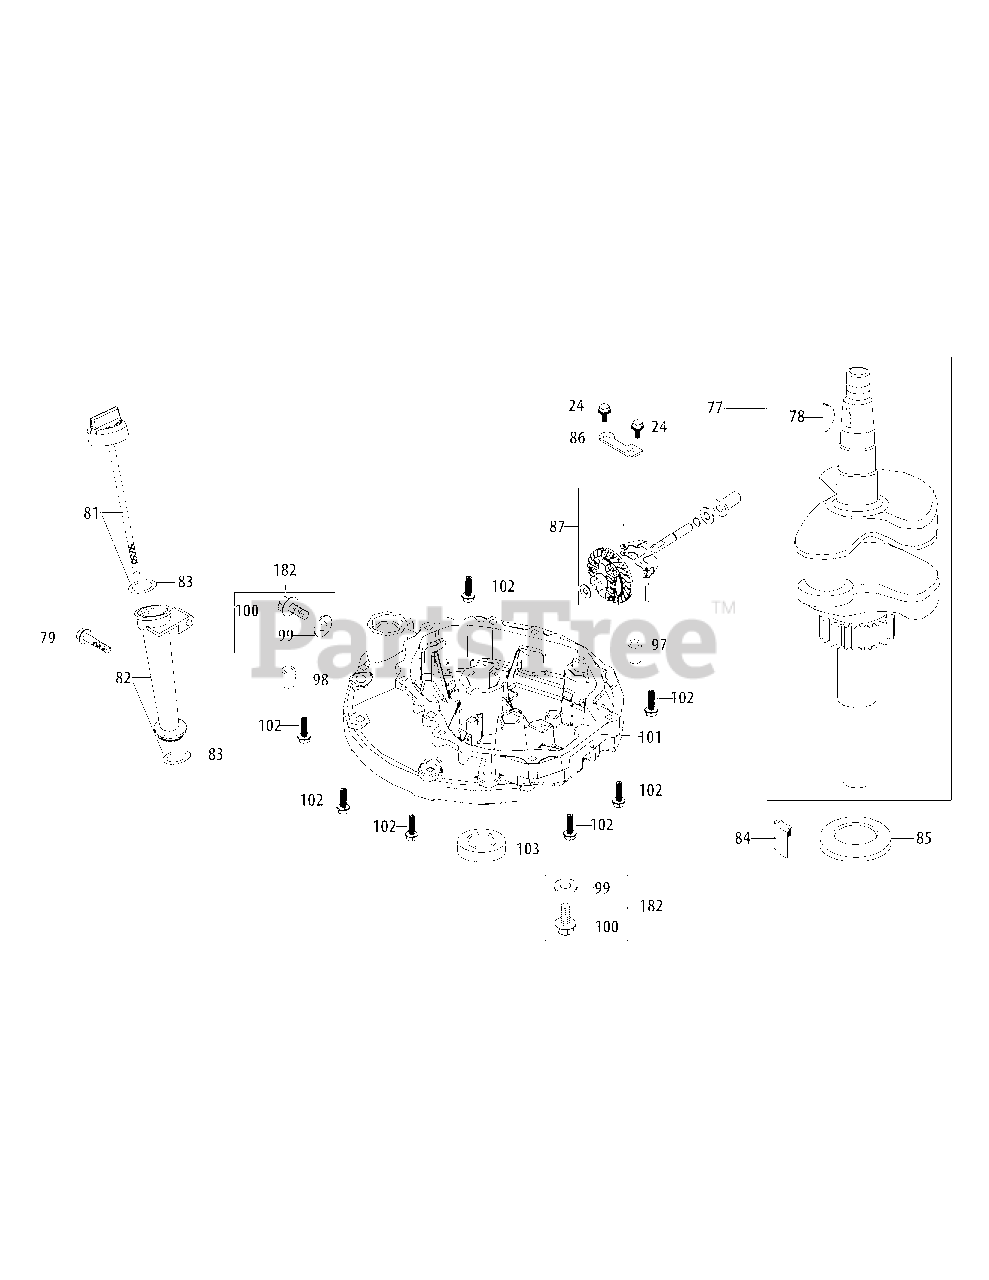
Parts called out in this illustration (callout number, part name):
24	Bolt M6X14
77	Crankshaft Assembly
78	Woodruff Key
79	Bolt M6X35
81	Dipstick Assembly
82	Oil Fill Tube
83	Dipstick / Oil Fill Tube O-Ring
84	Oil Return Seal
85	Crankshaft Thrust Washer
86	Governor Gear Mounting Plate
87	Governor Gear/Shaft Assembly
97	Crankcase Cover Dowel Pin 7×14
98	Crankcase Cover Dowel Pin 9×14
99	Oil Drain Plug Washer
100	Oil Drain Plug
101	Crankcase Cover
102	Bolt M6X28 P65 Crankcase
103	Lower Crankshaft Seal
182	Oil Drain Plug & Washer Assy
